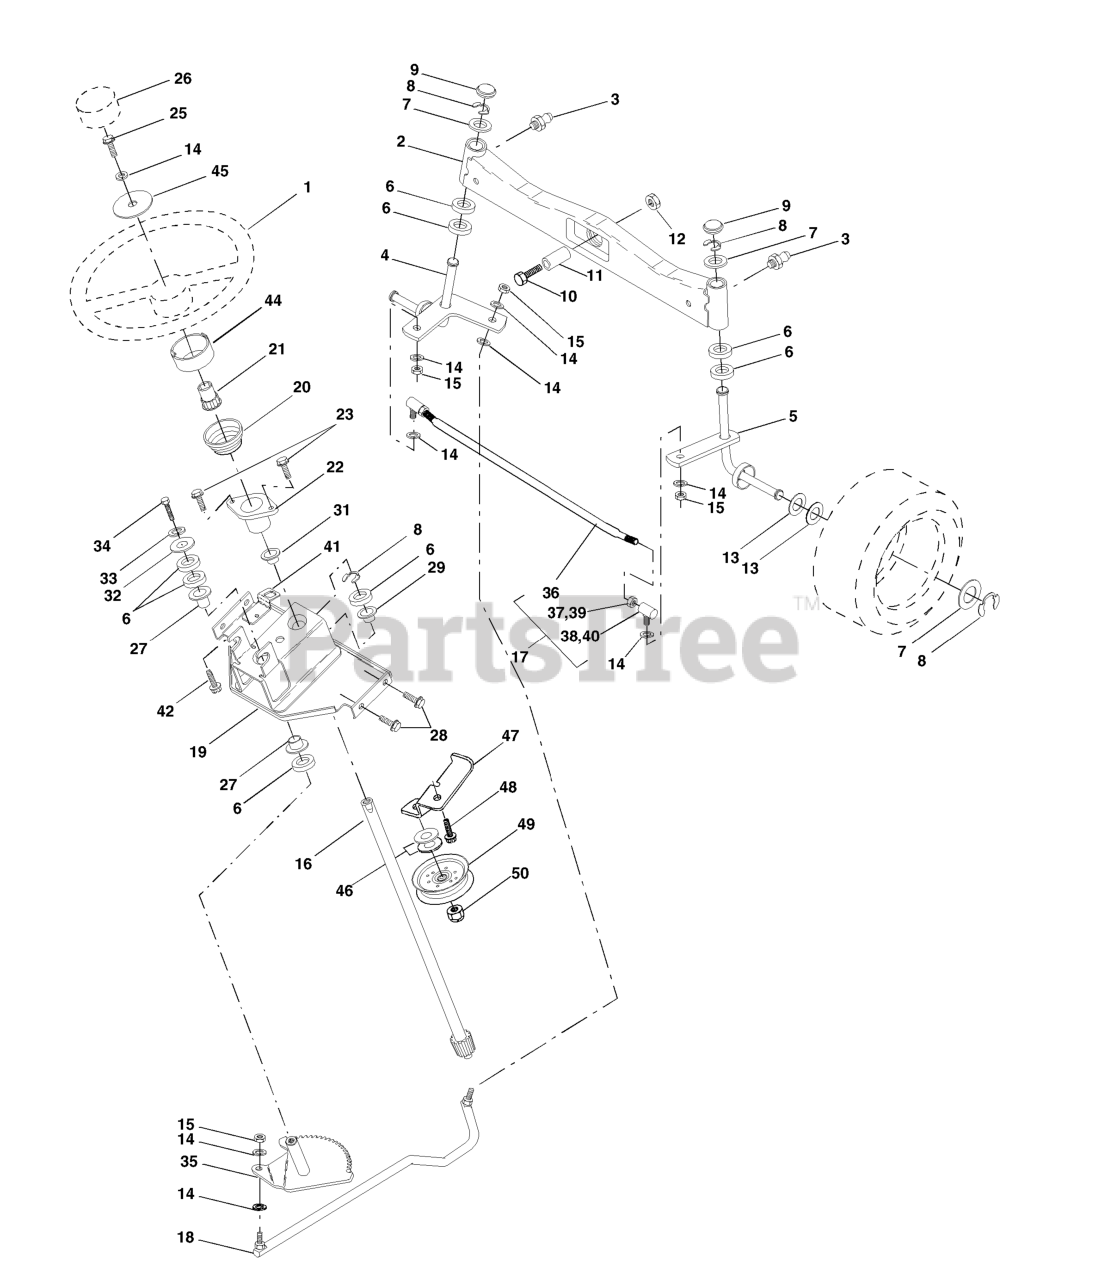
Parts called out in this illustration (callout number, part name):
1	STEERING WHEEL
2	AXLE.FRONT.CAST.MACHINE.W/ZERK
3	ZERK M
4	SPINDLE ASSY LH
5	SPINDLE ASM RH
6	THRUST WASHER
9	CAP.SPINDLE.BLACK
10	Bolt, Fin Hex 5/8-11 x 2-3/4
11	TUBE, PIVOT AXLE
12	NUT-LOC,FLANGE LT
14	WASHER, LOCK 3/8
15	GRIPCO NUT
16	SHAFT ASM, STEERING
17	ROD ASSY/TIE BALL
18	DRAGLINK, BALL JOINT (3SPG1401
19	SUPPORT ASM., STEERING VGT
20	BOOT, STEERING
21	STEERING WHEEL ADAPTOR
22	BUSHING, STRG. BLK
23	SCREW.TT.#10-32X.5.3/8.FLANGE
25	BOLT
26	CAP.WHEEL.STEERING.GREY
27	BRNG T
28	SCREW, 3/8-16X3/4
29	BEARING-FLANGE GT
31	BUSHING.NYLINER.
33	WASHER.LOCK.HVY.HLCL.SPR.5/16
34	BOLT.FIN.HEX.5/16-18X3/4
35	GEAR.ASM.SECTOR.
36	TIE ROD
38	JOINT
41	BRACKET INTERLOCK
42	Screw 5/16-18 x 1/2
44	EXTENSION STEERING PREMIUM
45	Washer 13/32 x 1-1/2 x 11 Ga.
46	WASHER
47	BRACKET ASM, IDLER STATIONARY
48	SCREW 3/8-16X3/4
49	PULLEY.IDLER.FLAT.46.PR.DR.
50	NUT LOCK FLG 3/8-16 UNC
